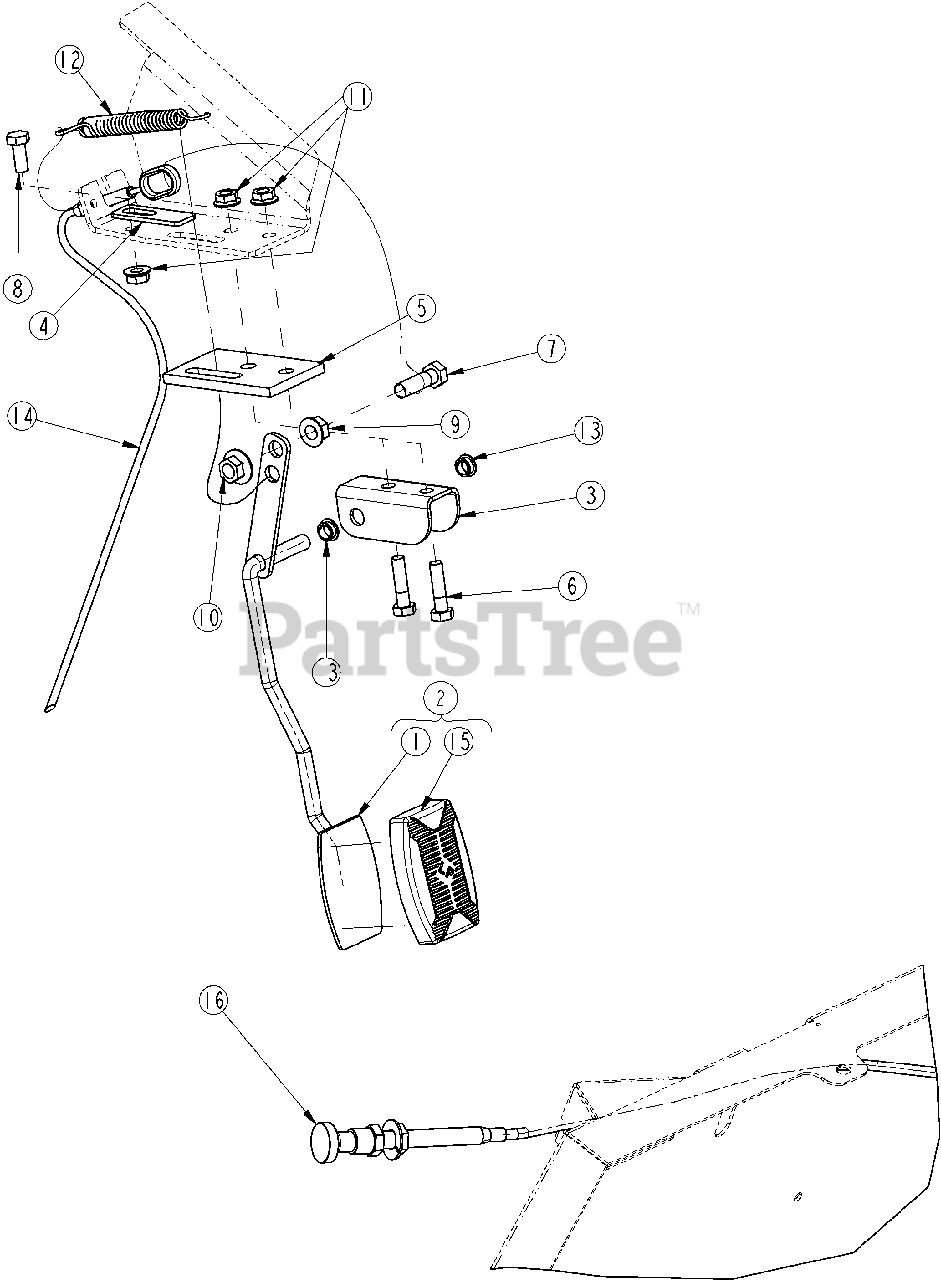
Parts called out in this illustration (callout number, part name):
1	GAS PEDAL WELDMENT
2	GAS PEDAL W/PAD ASSEMBLY
3	GAS PEDAL MOUNT
4	GAS PEDAL ADJUSTMENT PLATE
5	BODY MOUNT SPACER .375 THICK Use as needed
5	BODY MOUNT SPACER .25 THICK Use as needed
6	HHCS 5/16-18X1 1/4 GR5
7	BOLT, HEX 3/8-16 X 1 1/4 GR5
8	BOLT, HEX 5/16-18 X 3/4 GR5 YELLOW DIE
9	NUT, SERRATED FLANGE 3/8-16 PLT
10	NUT MAC-LOK FLG 3/8-16 GR F
11	NUT HEX LOCK 5/16-18 FLG.
12	SPRING EXT .5OD .075W 2.75LG
13	BUSHING NYLON 3/8ID (SNAP IN)
14	THROTTLE CABLE
15	BRAKE/ACCELERATOR PEDAL RUBBER
16	THROTTLE CABLE
